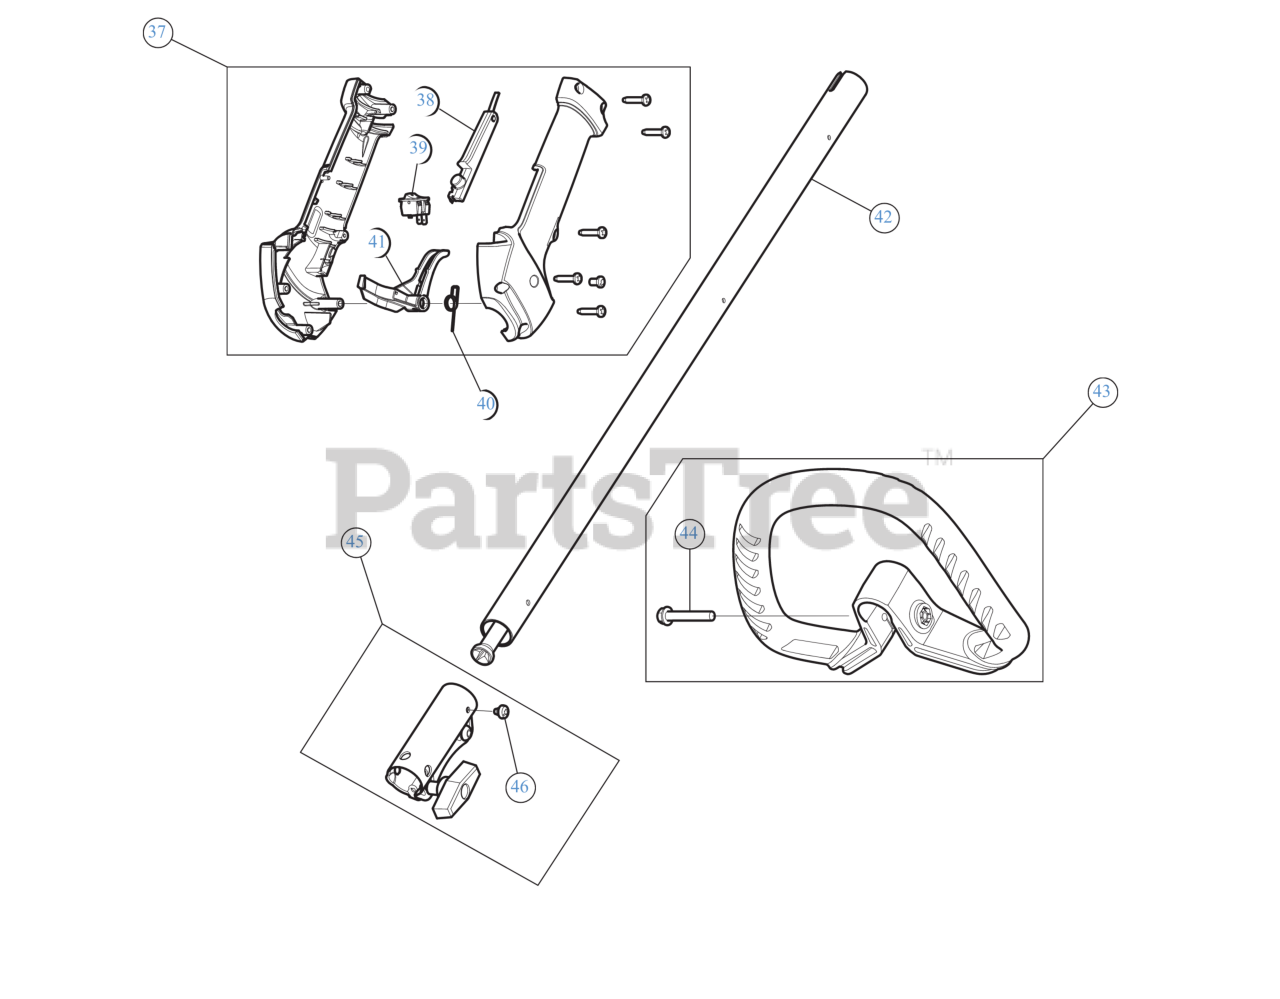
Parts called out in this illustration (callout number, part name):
37	THROTTLE GRIP ASSEMBLY
38	LEVER LOCK OUT
39	SW, MOMENTARY ON/O
40	TRIGGER SPRING
41	THROTTLE TRIGGER
42	BOOM ASSEMBLY UPR
43	HANDLE ASSEMBLY
44	BOLT 1/4-20X1 1/2
45	SPLIT BOOM COUPLER KIT
46	SCREW, 10-32X.250 TA
